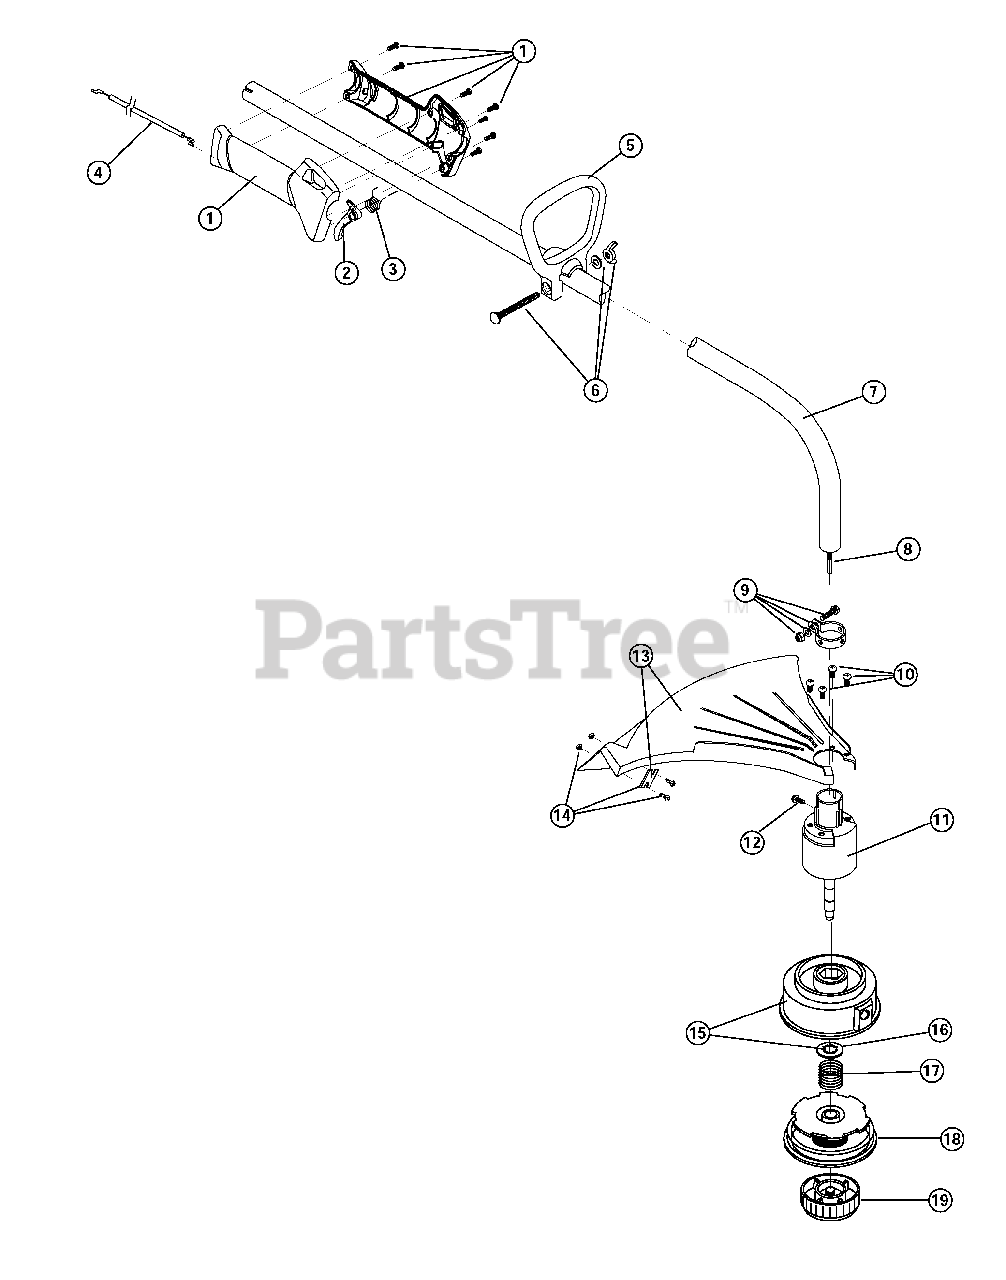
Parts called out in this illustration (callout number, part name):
1	Throttle Housing & Trigger Assembly
2	Throttle Trigger Spring
3	Throttle Trigger
4	Throttle Cable Assembly
5	D-Handle Assembly
6	D-Handle Hardware
7	Drive Shaft Housing Assembly
8	Flexible Drive Shaft
9	Lower Clamp Assembly
10	Shield Mounting Screw
11	Bushing Housing Assembly
12	Anti-Rotation Screw
13	Shield and Blade Assembly
14	Blade Assembly
15	Outer Spool w/ Retainer
16	Retainer
17	Spring
18	Inner Reel
19	Bump Head Knob Assembly
